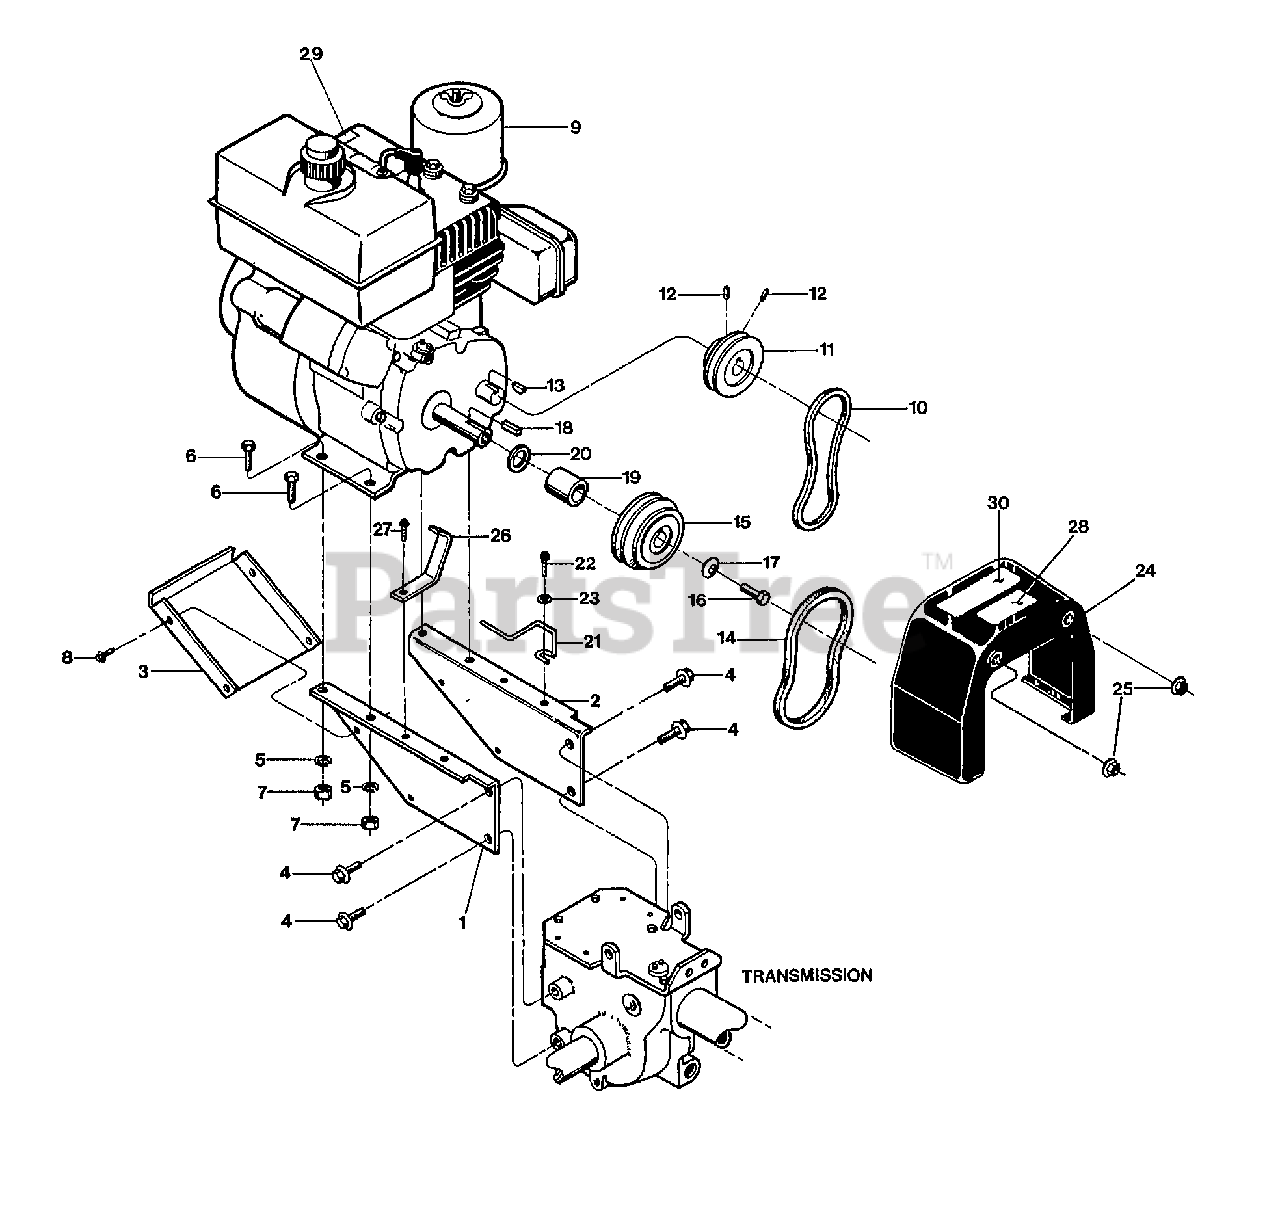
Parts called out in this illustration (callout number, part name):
1	BRKT-ENG LT P4
2	BRKT-ENG RT PNT
3	PAN-ENG BRKT PNT
4	SCR-HFLK 5/16-18X.75 ZP
5	WASHER-LK .312 ZP
6	SCR-HHC 5/16-18X.75 GR 5 ZP
7	NUT-HEX 5/16-18 ZP
8	SCR-HW M10-32X.5 THRD ROLL
9	ENGINE, TECUMSEH, 6HP RECOIL START,
10	BELT-V REV DR ECONO (SEE V-BELT BELOW)
11	PULLEY-REV MACH
12	SCR-SS 1/4-20 X .25 (SECURES REVERSE ENGINE PULLEY)
13	KEY-WOODRUFF #5
14	BELT-V GROOVE FWD SMFRAME
15	PULLEY-ENGINE MACH
16	SCR-HH 3/8-24X1.0 G5 ZP
17	WASHER-.994X.413X.145
18	KEY-.188 SQX1.0
19	SPACER-.937X.755X.938
20	SHIM-1.0X.7656X.031
21	GUIDE-BELT FWD
22	SCR-HWH 1/4-20 X .75 STH
23	WASHER-FLAT 1/4 SAE
24	COVER-BELT W/DECALS (INCL. 28 & 30)
25	NUT-HFLK 5/16-18 ZP
26	GUIDE-BELT REV PNT
27	SCR-HWH 1/4-20 X .5 STH
28	DECAL-BELT POSITION
29	DECAL-STARTING STABIL
30	DECAL-BELT COVER OPC
